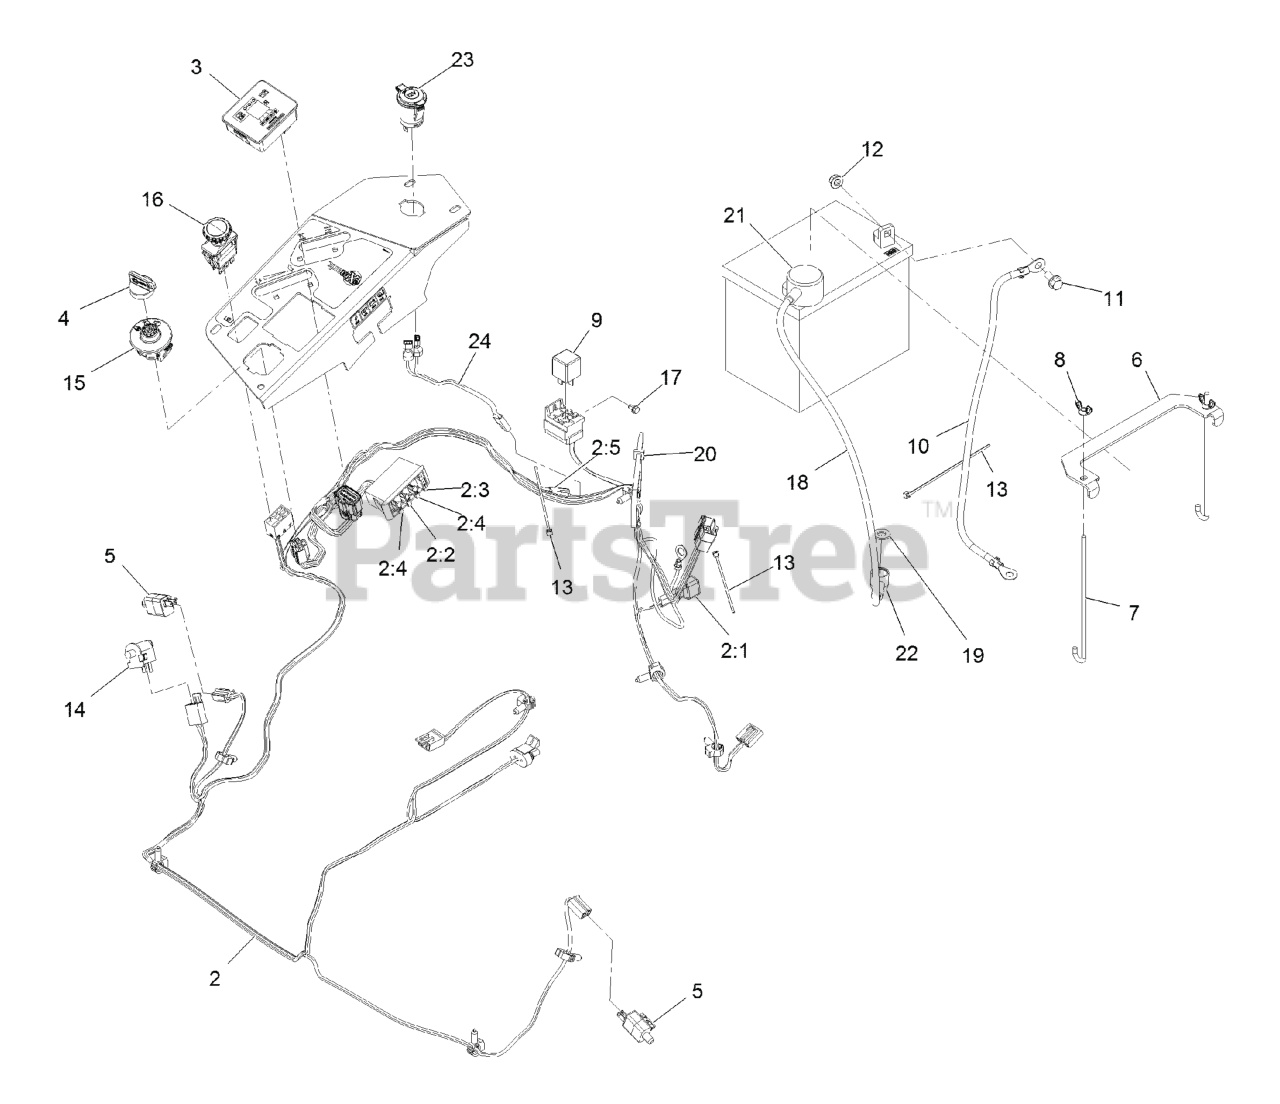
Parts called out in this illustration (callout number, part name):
2	HARNESS-WIRE, MAIN
2:2	FUSE-BLADE, 10 AMP
2:3	FUSE-BLADE, 15 AMP
2:4	FUSE-BLADE, 25 AMP
2:5	CAP-PLUG
3	FUEL/HOUR METER ASM
4	KEYS-IGNITION (SPARE PAIR
4	KEY-IGNITION
6	STRAP-TIE DOWN, BATTERY
7	BOLT-HOLDDOWN
8	WINGNUT
10	CABLE-BATTERY, NEGATIVE
11	SCREW-HHF
12	NUT-HF, NI
13	TIE-CABLE
14	SWITCH-BAIL
15	SWITCH-IGNITION
16	SWITCH-PTO, 10 AMP
17	SCREW-HWH
18	CABLE-BATTERY, POSITIVE
19	WASHER-FLAT
20	TIE-PLASTIC
21	INSULATOR-BATTERY
22	INSULATOR-SOLENOID
23	PORT-POWER, 12V
24	HARNESS, RECEPTACLE 12V
